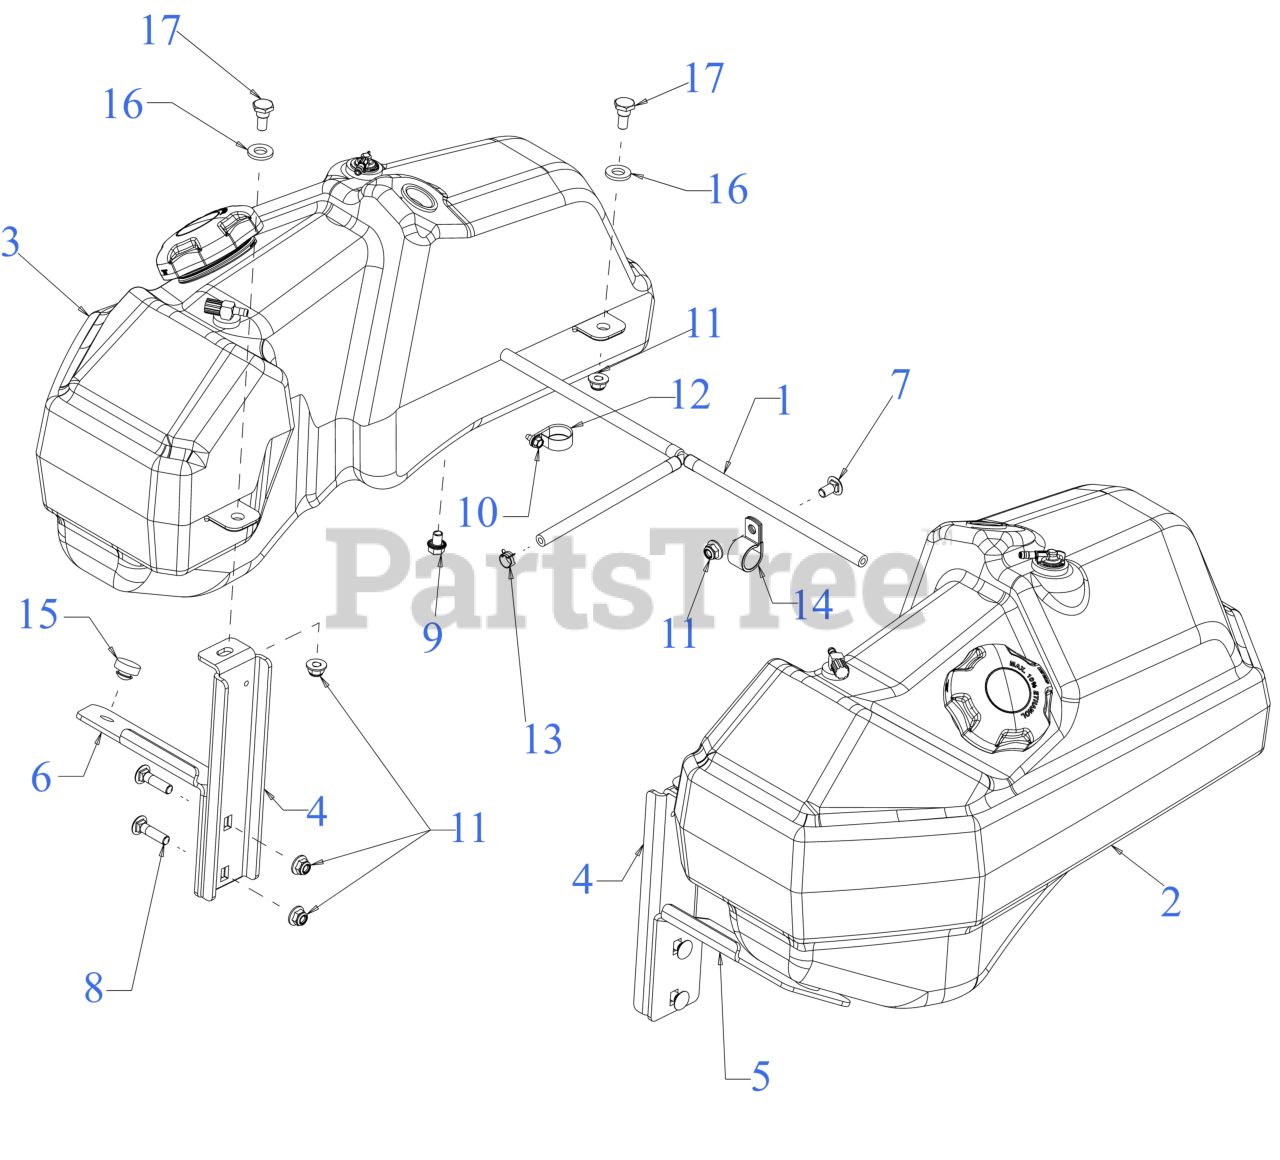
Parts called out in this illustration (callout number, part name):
1	FUEL LINE ASSEMBLY
2	FUEL TANK (RH) 7.25 GAL
3	FUEL TANK (LH) (7.25 Gal)
4	FUEL TANK MOUNTING BRACKET
7	CARRIAGE BOLT 3/8-16 x .750 GR5
8	CARRIAGE BOLT 3/8-16 x 1.50
9	SCREW 3/8-16 x .500 GR5
10	SCREW 1/4-20 X.500
12	DRAIN HOSE CLAMP
14	HOSE CLAMP 1.0"
15	RUBBER BUMPER 1.000 x .313
16	FLAT WASHER .510 x 1.000 x .125
17	SHOULDER SCREW .498 DIA x .340
